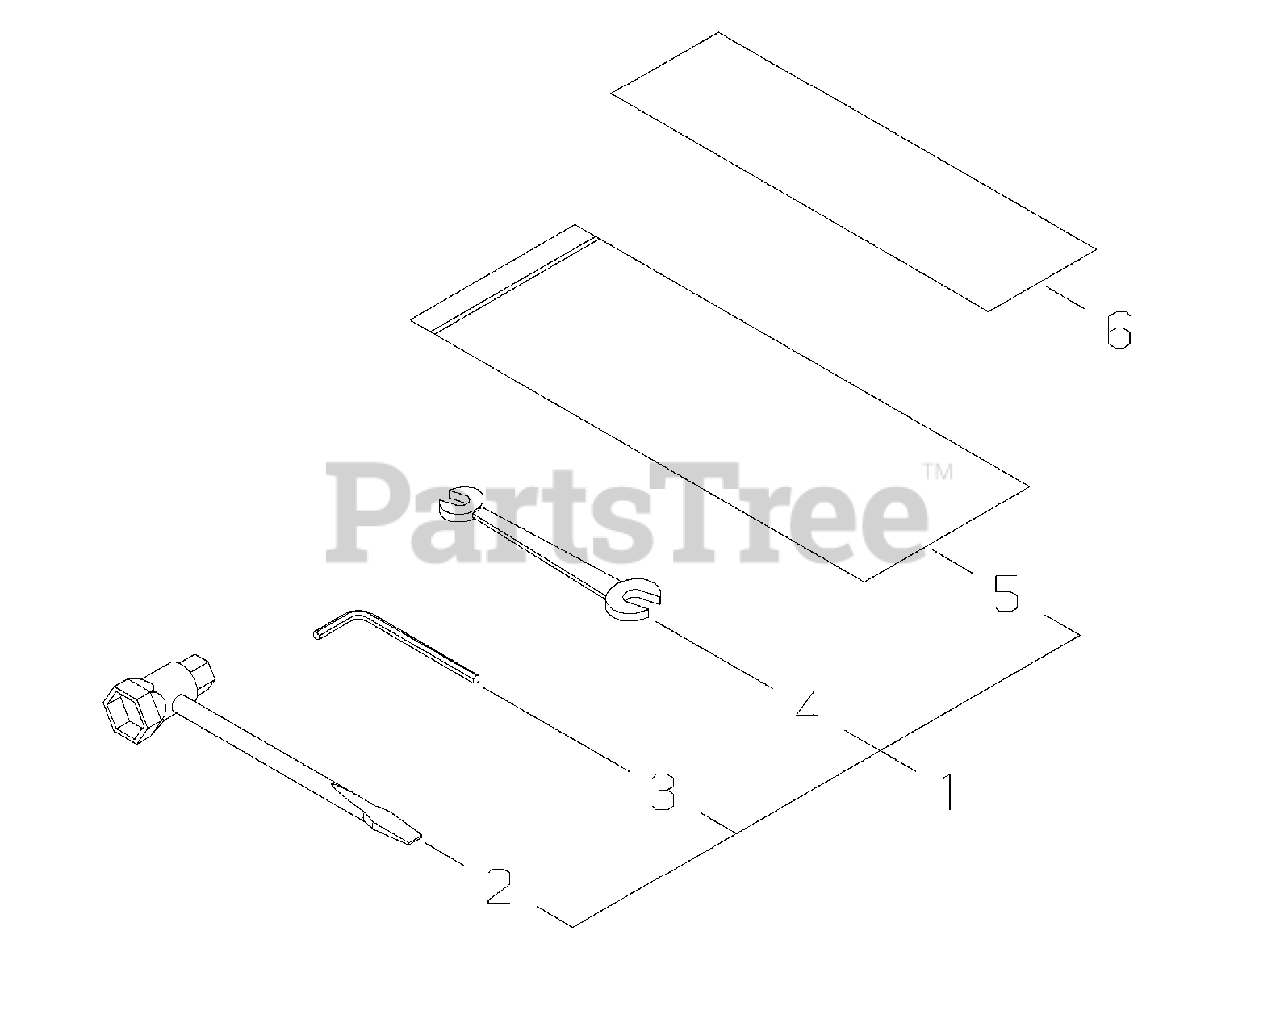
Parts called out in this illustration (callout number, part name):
1	TOOL KIT
2	T-WRENCH
3	HEX KEY - 4mm
4	SPANNER - 8X10mm
5	BAG, TOOL
6	LABEL - CAUTION
